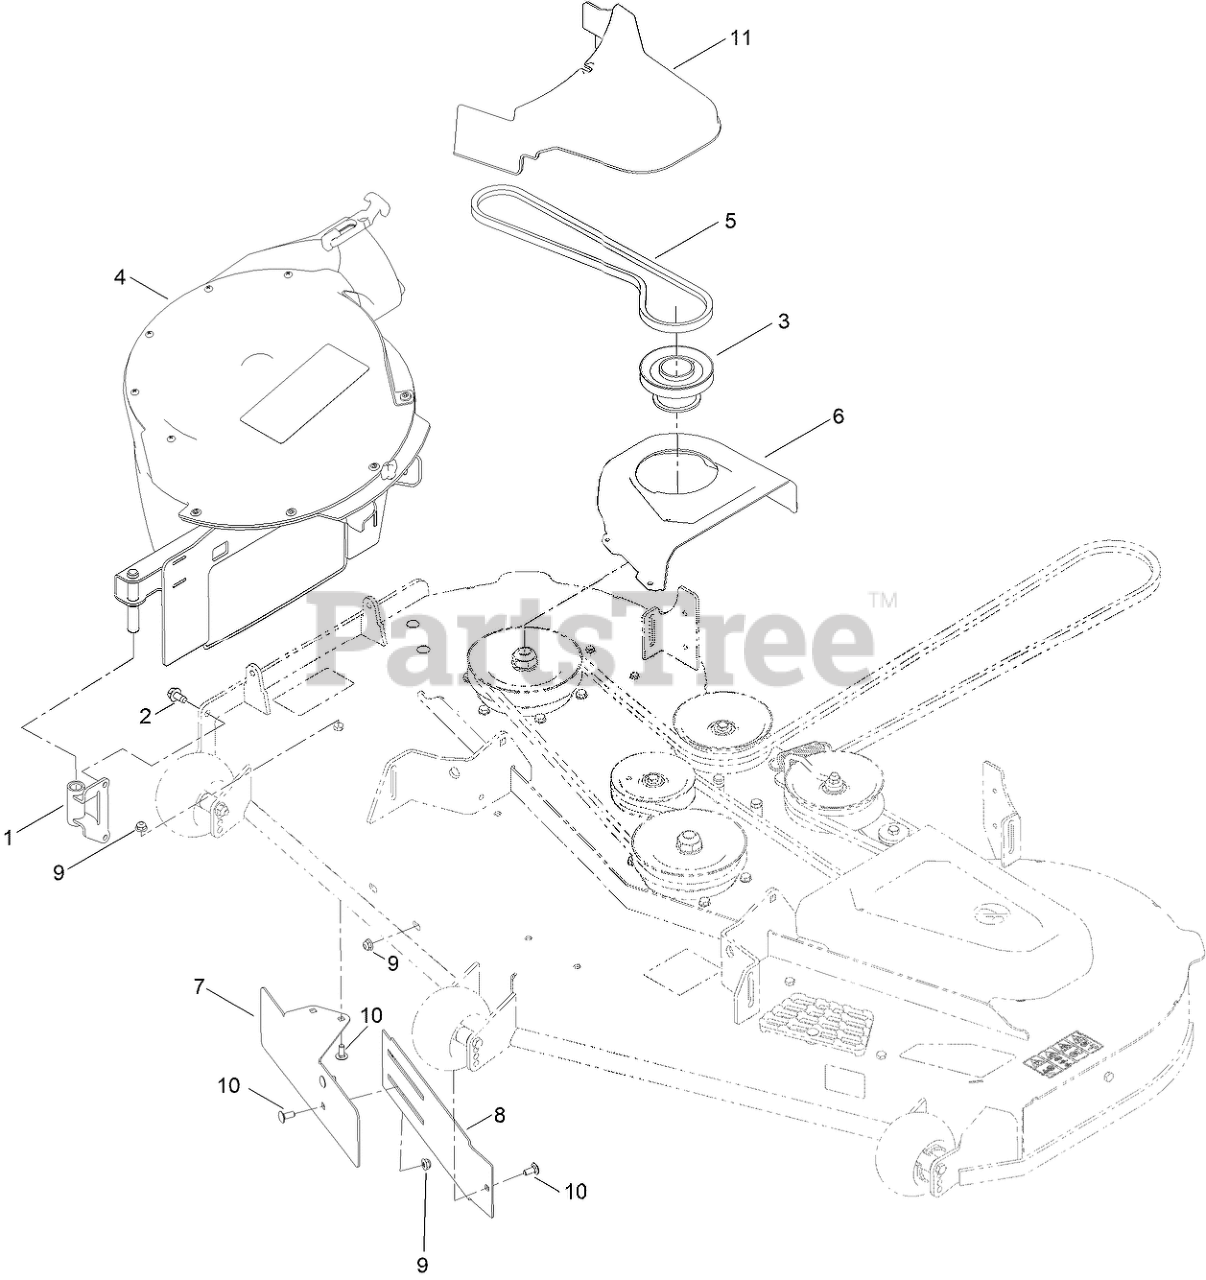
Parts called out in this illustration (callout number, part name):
1	PIVOT-BLOWER
2	SCREW-HWH
3	PULLEY-BAGGER
4	Blower Housing Assembly
5	BELT-V
6	COVER-BELT, RH
7	BAFFLE-OUTER
8	BAFFLE-INNER
9	NUT-HF
10	BOLT-CARR
11	COVER-BAGGER, POWERED
